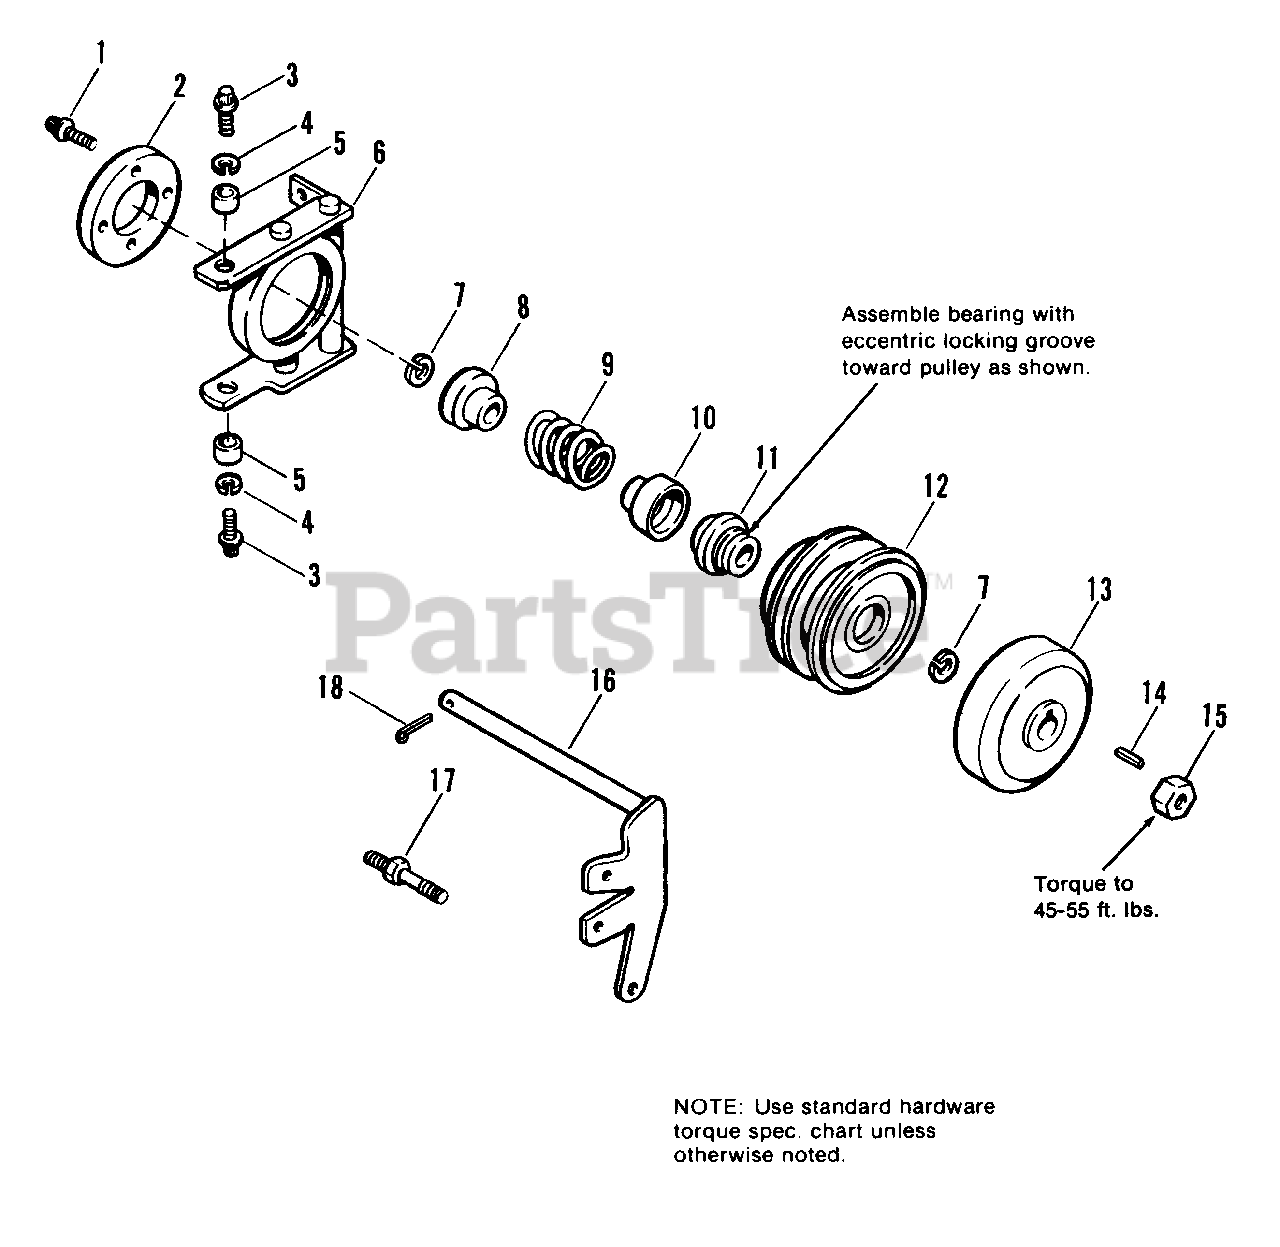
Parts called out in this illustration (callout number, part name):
1	CAPSCREW, Socket Hd., 1/4-20 x 5/8
2	BRAKE, Disc
3	SCREW, Thd. Forming
4	LOCKWASHER, 5/16
6	PIVOT ASSY.
7	RING, Retaining
8	GUIDE, Spring
10	GUIDE, Spring
11	BEARING ASSY.
13	PLATE ASSY., Clutch
14	KEY
15	LOCKNUT, Hex, 3/4-16
16	ARM ASSY., Pivot
18	PIN, Cotter, 3/16 x 1-1/2
